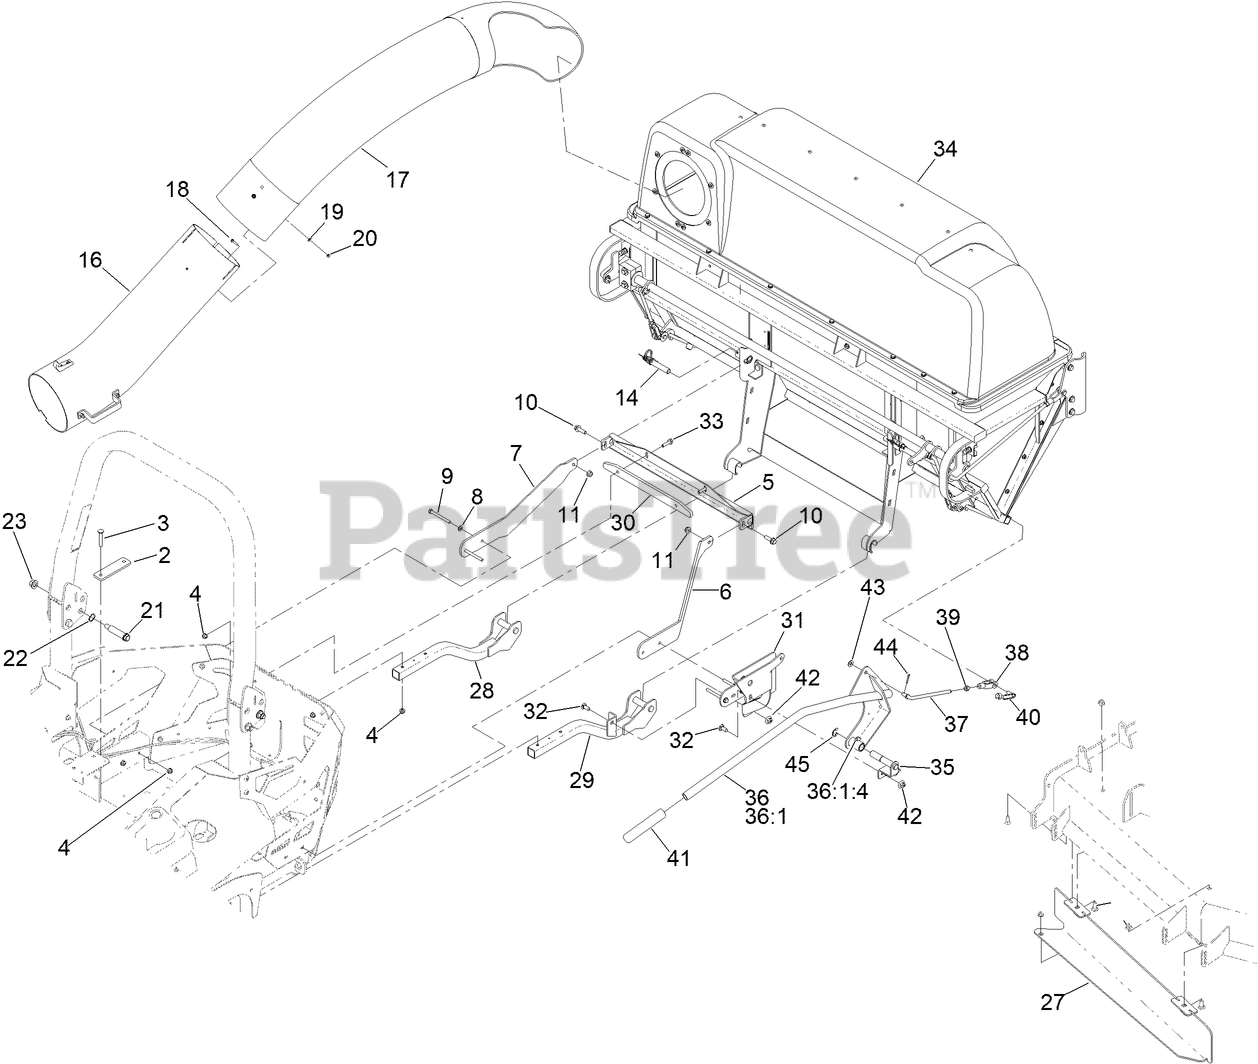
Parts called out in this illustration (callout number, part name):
2	PLATE-BACKER
3	BOLT-CARR
4	NUT-HF, NI
5	SUPPORT-BAGGER, UPPER
6	BRACKET-UPPER, LH
7	BRACKET-UPPER, RH
8	WASHER-PLAIN
9	SCREW-HH
10	SCREW-HHF
11	NUT-HF, NI
14	PIN-MOUNT, BAGGER
16	LOWER TUBE ASM
17	TUBE-UPPER
18	SCREW-HWH
19	WASHER-FLAT
20	NUT-LOCK, NI
21	BOLT-SHOULDER
22	WASHER-WAVE
23	NUT-LOCK
27	BAFFLE-BAGGER, 60
28	SUPPORT-LOWER, RH [BLACK]
29	SUPPORT-LOWER, LH [BLACK]
30	PLATE-SUPPORT
31	PIVOT MOUNT
32	SCREW-CARR
33	SCREW-HHF
34	DFS ASM
35	PIN-HANDLE
36	HANDLE ASM
36:1	HANDLE ASM
36:1:4	FITTING-GREASE
37	LINK-HANDLE
38	YOKE-LINKAGE, BRAKE
39	NUT-HEX
40	PIN-SPRING, CLEVIS
41	HANDLE-GRIP
42	NUT-FLANGE, NI
43	WASHER-FLAT
44	PIN-COTTER
45	E-RING
